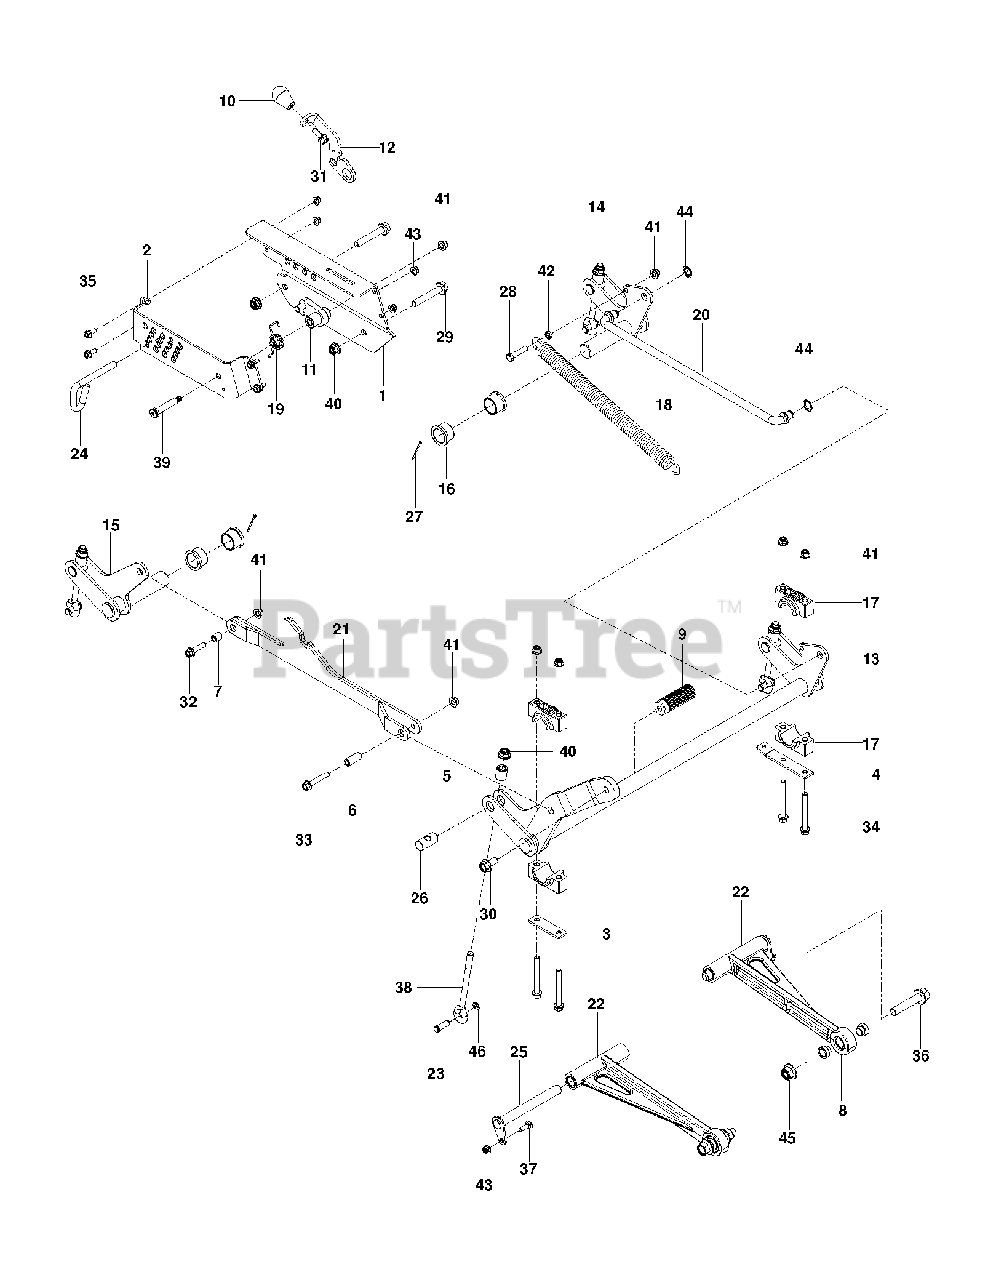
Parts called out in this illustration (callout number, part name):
1	PLATE, HEIGHT INNER ORG
2	PLATE, HEIGHT OUTER ORG
3	PLATE, PILLOW BLACK
4	PLATE, SPRING ANCHOR
5	SPACER, EYEBOLT
6	SPACER, FRONT LIFT STRAP
7	SPACER, REAR LIFT STRAP
8	SPACER, STRUT
9	PEDAL, DECK HEIGHT
10	KNOB - SHIFT
11	LATCH, TRANSPORT WLDMT
12	LEVER, TRANSPORT RELEASE
13	SHAFT DECK LIFT FT
14	SHAFT, LIFT LEFT REAR
15	SHAFT, LIFT RIGHT REAR
16	BUSHING, FLANGE 1.25 X 1.0
17	BLOCK, PILLOW
18	SPRING, EXTENSION
19	SPRING, TORSION
21	WELDMT, DECK STRAP
22	ASSEMBLY, STRUT
23	PIN, 7/16 CLEVIS
24	PIN, HEIGHT
25	PIN, STRUT
26	PIN, TRUNION, EYEBOLT
27	COTTER PIN 1/8 X 2
28	HCS 3/8-16 X 1 3/4 GR5
29	HFFS 1/2-13 X 3 GD 5 ZD
30	HHFS 1/2-13 X 1 GR5 ZD
31	HHFS 3/8-16 X 1 GRD 5 ZD
32	HHFS 3/8-16 X 1.50 GR5 ZD
33	HHFS 3/8-16 X 2-1/4 GR 5 ZD
34	HHFS 3/8-16 X 3.5 GD 5 ZD
35	HHFS 5/16-18 X 3/4
36	HHFS 5/8-11 X 3.0 GD 8 ZD
37	RHSNB 5/16C X 1
38	EYEBOLT, DECK LIFT
39	BOLT, SHOULDER, 1/2 X 2.25
40	NUT, 1/2-13 HEX FLG NYLOC ZD
41	NUT 3/8-16 HEX FLG NYLOC ZD
42	NUT 3/8-16 HEX JAM
43	5/16-18 NYLOC FLANGE NUT
44	NUT 5/8 PUSH
45	NUT 5/8-11 FLG NYLOC ZD
46	RING, E, 7/16
